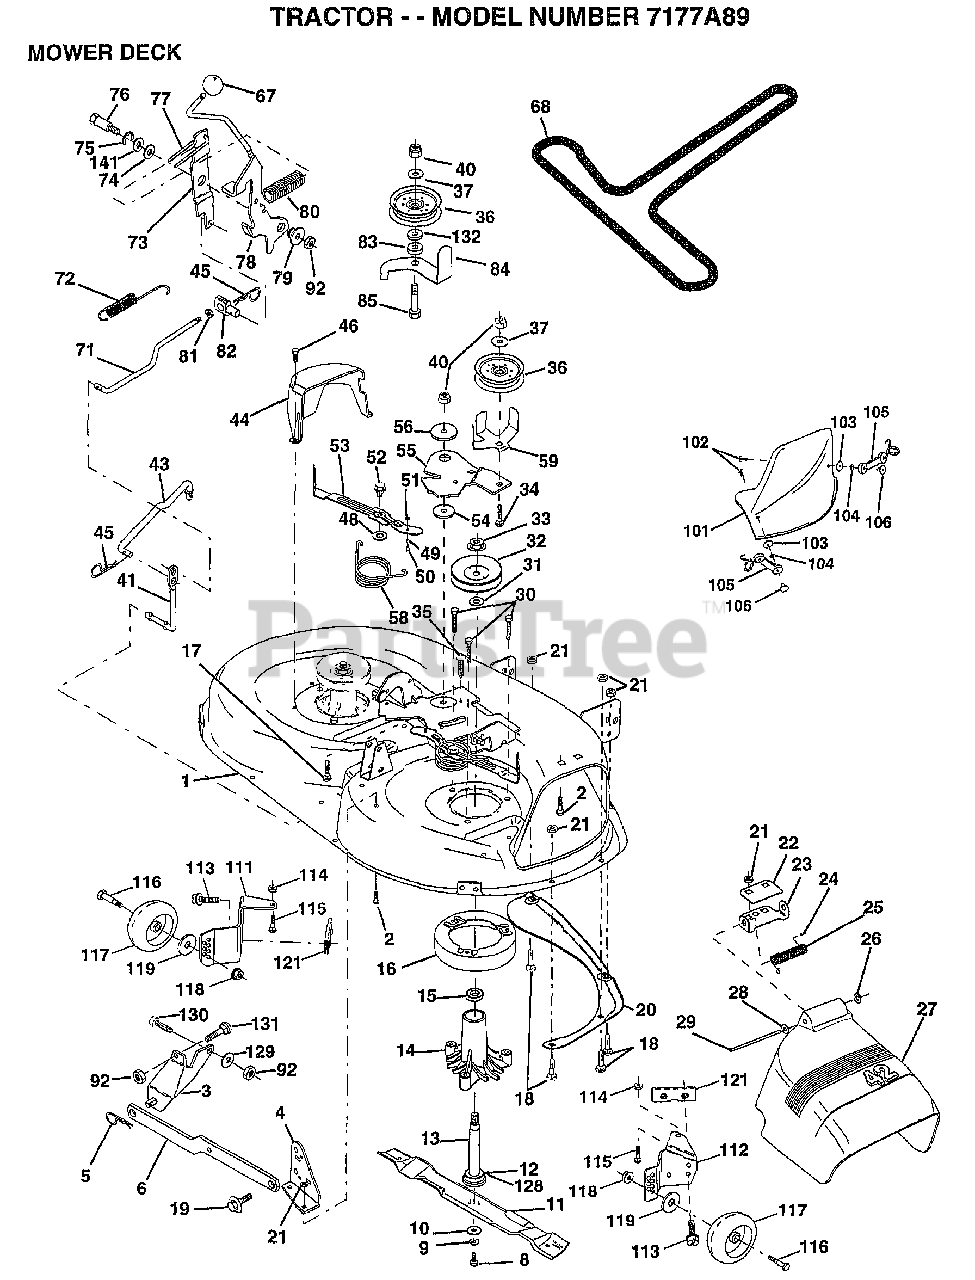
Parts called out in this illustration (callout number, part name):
1	DECK.WELD.42.
2	BOLT
3	BRKT ASM SWAY BAR
4	BRKT DECK SW BAR
8	BLADE BOLT
10	WASHER.HARD.BLADE
11	"BLADE.42"" MULCHER"
12	BEARING.BALL
14	HSG ASM MANDREL
15	BEARING
16	STRIPPER RND MWR
17	BOLT RDHD 3/8-16
18	BOLT
19	BOLT SHD 5/16-18
20	BAFFLE VORTEX 42
22	STIFFENER BRKT
23	DEFLECTOR BRKT
24	CAP-SLEEVE LT
25	SPRING TORSION
26	NUT PUSH M
27	DEFLECTOR.SHIELD
28	WASHER
29	HINGE ROD
30	"SCREW-THD ROLL,WA"
31	WASHER
32	PULLEY.MANDREL.42
34	BOLT
35	XMAS TREE FASTNER
36	FLAT IDLER PULLEY
37	WASHER
41	PIVOT ROD
43	ROD CLUTCH W/NIBS
44	GUARD MAND LH BLK
46	SCREW.1/4-20X5/8
48	HARD SMALL WASHER
49	ROLLER ASM-CAM
50	SHOULDER BOLT
51	LOCKNUT
52	BOLT.SHLD.5/16-18
54	HARDENED WASHER
55	ARM-IDLER
56	SPACER RETAINER
58	SPRING TORSN BRAK
59	GUARD IDLER TUV
67	KNOB.RD.7/16-14
68	BELT.V.T-PATH
71	ROD CLUTCH 38/42
72	RETURN SPRING
73	CLUTCH ARM SECOND
74	WASHER
75	RING
76	SHOULDER BOLT
77	SPRING KEEPER
78	LEVER.ASM.CLUTCH
79	BUSHING
80	SPRING.CLUTCH.MWR
81	NUT
82	TRUNION ADJ
83	WASHER
84	"KEEPER-BELT,FIXED"
85	BOLT RDHD 3/8-16
92	NUT
101	"COVER.MULCH.42"""
102	SCREW
103	WASHER #10
104	LOCKWASHER
105	LATCH ASSY.BAGGER
106	WELDNUT
111	BRACKET.GWHL.LH.
112	BRACKET.GWHL.RH.
113	SCREW
116	BOLT.SHOULDER
117	WHEEL GAGE DONUT
118	LOCKNUT
119	WASHER
121	BRACKET.EXTRD.GWL
128	WASHER.FELT.
129	WASHER
130	BOLT
132	WASHER GT
141	WASHER .T
